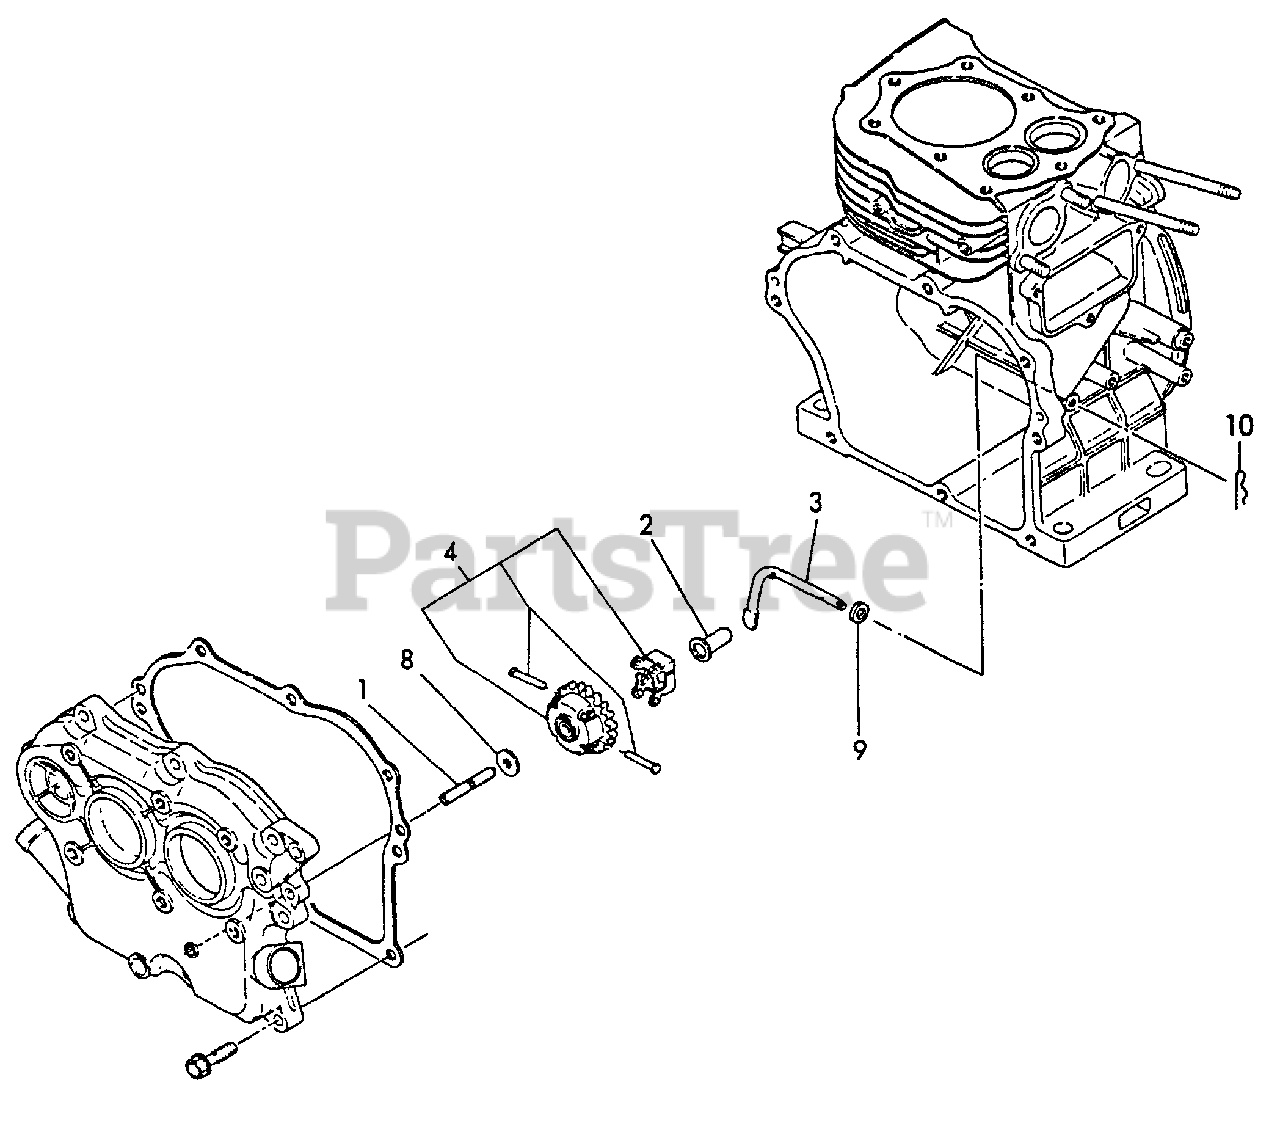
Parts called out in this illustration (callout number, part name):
1	SHAFT, GOVERNOR
2	SPINDLE, GOVERNOR
3	YOKE, GOVERNOR
4	GOVERNOR GEAR ASSY
8	WASHER
9	WASHER - 6
10	PIN - 6 -- SNAP
